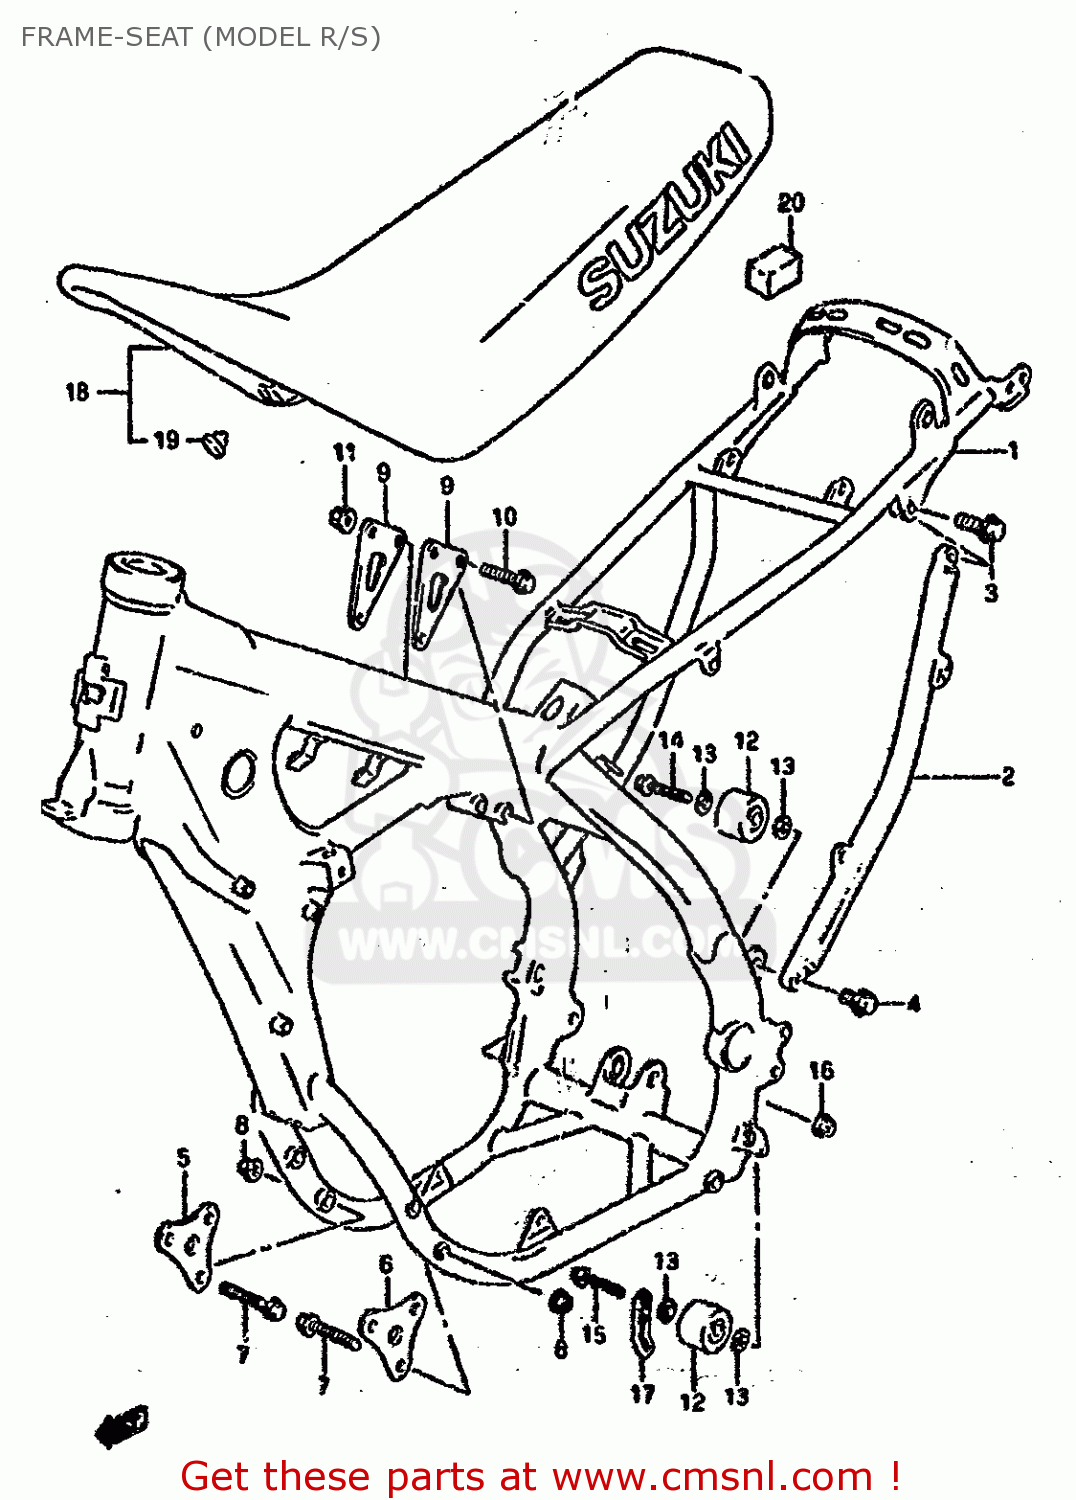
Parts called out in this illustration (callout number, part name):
1	FRAME
2	TUBE,FRAME SIDE,L
3	BOLT
4	BOLT, LOWER
5	PLATE,ENG MTG FR
6	PLATE,ENGINE MOUNTING
7	BOLT
8	NUT
9	PLATE,ENG MTG UPR
10	BOLT(8X45)
11	NUT
12	ROLLER,CHAIN
13	WASHER
14	BOLT(8X41)
15	BOLT(8X45)
16	NUT
17	CLAMP
18	SEAT ASSEMBLY
19	CUSHION
20	CUSHION,SEAT
